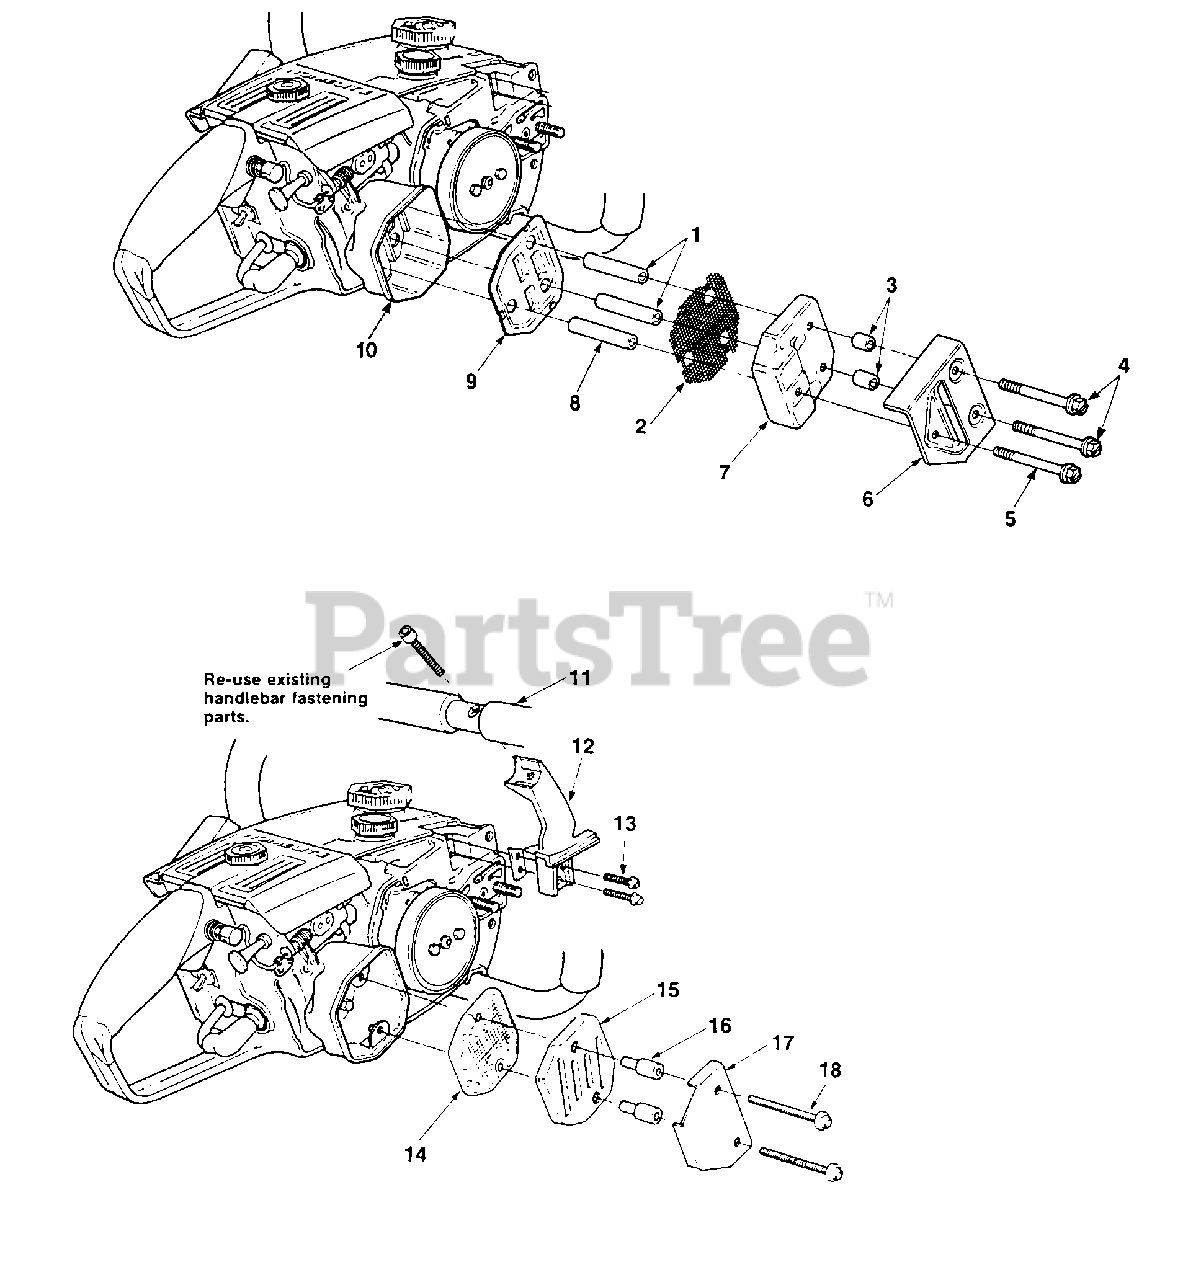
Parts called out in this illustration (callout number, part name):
1	SPACER- Split 2"
2	SCREEN- Muffler
3	SPACER- Split 5/16"
4	SCREW- Mach. hex hd. (10-32 x 2 7/8)
5	SCREW- Mach. hex hd. (10-32 x 2 5/8")
6	DEFLECTOR- Muffler
7	CAP- Muffler
8	SPACER- Split 2 1/8"
9	BAFFLE- Muffler
10	MUFFLER- Body
11	HANDLE BAR
12	BRACKET- Handle bar
13	SCREW- (#10-32 x .625)
14	ARRESTOR- Spark
15	CAP- Muffler
16	SPACER- Muffler
17	SHIELD- Muffler
18	SCREW- Hex washer (10-32 x 1.5)
